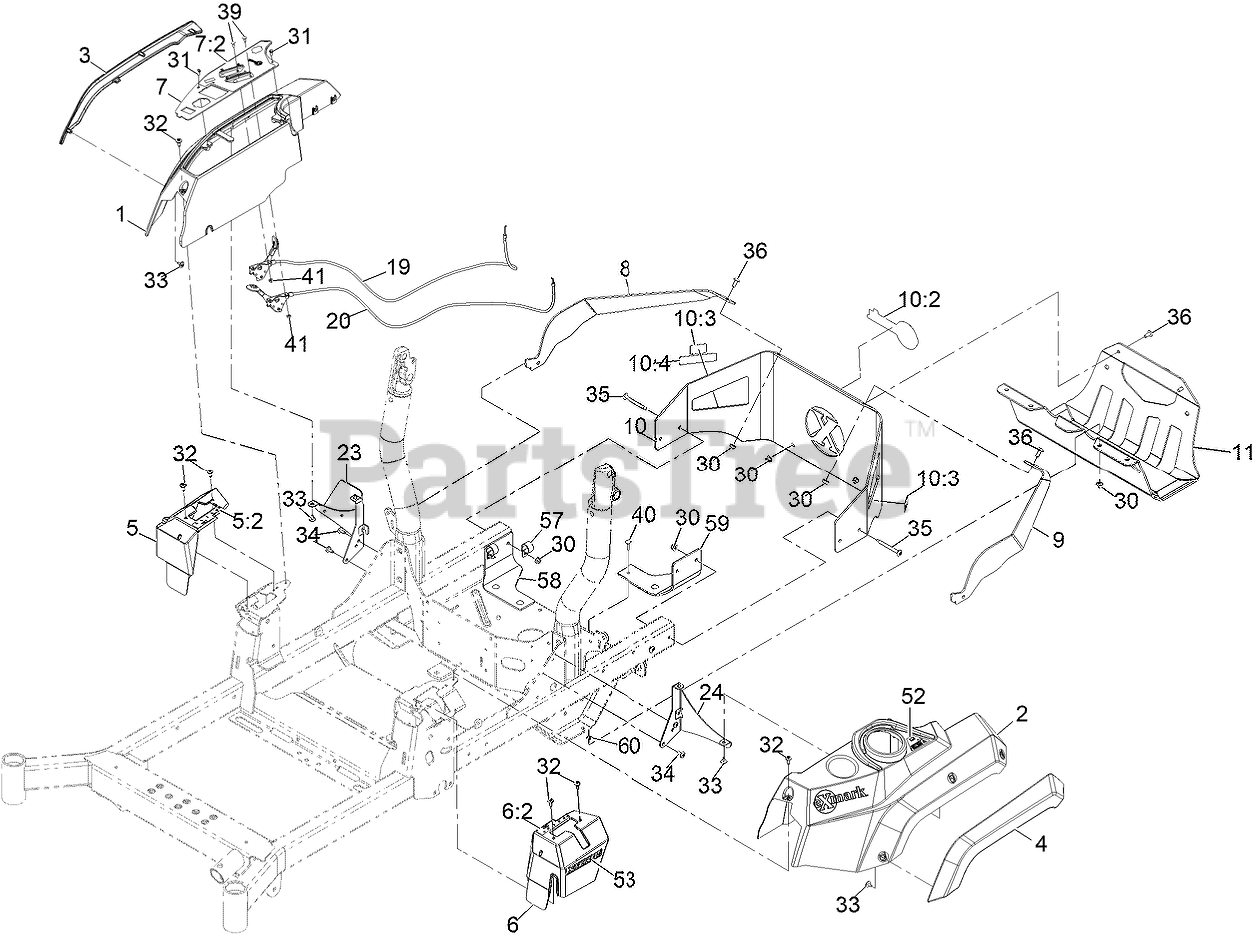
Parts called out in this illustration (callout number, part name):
1	CONSOLE-EXMARK, RH
2	CONSOLE, LH
3	FENDER-RH
4	FENDER-LH
5	COVER-CONTROL, MOTION (RH
5:2	Decal-Control, Motion (RH)
6	COVER-CONTROL, MOTION (LH
6:2	Decal-Control, Motion (LH)
7	ASM-CONTROL PANEL W/EXMARK DECAL
7:2	DECAL-CONTROL PANEL
8	SUPPORT-UPPER, RH
9	SUPPORT-UPPER, LH
10	REAR GUARD ASM
10:2	DECAL, EXMARK LOGO
10:3	DECAL-WARNING
10:4	DECAL-ARRESTOR, SPARK
11	GUARD-MUFFLER W/DEFLECTORS
19	ASM,CHOKE CABLE
20	ASM, THROTTLE CABLE
23	SUPPORT-CONSOLE, RH
24	BRACKET-CONSOLE, LH
30	NUT-HF, NI
31	SCREW-HWH
32	SCREW-SHOULDER
33	SCREW-TORX
34	SCREW-TORX
35	SCREW-TORX
36	SCREW-TORX
39	BOLT-CARR
40	SCREW-CARR
41	NUT-LOCK, NI
52	DECAL-FILL, FUEL
53	DECAL-X-SERIES
57	R-CLAMP
58	BRACKET-DECK SUPPORT, RH
59	BRACKET-DECK SUPPORT, LH
60	NUT-PUSH
